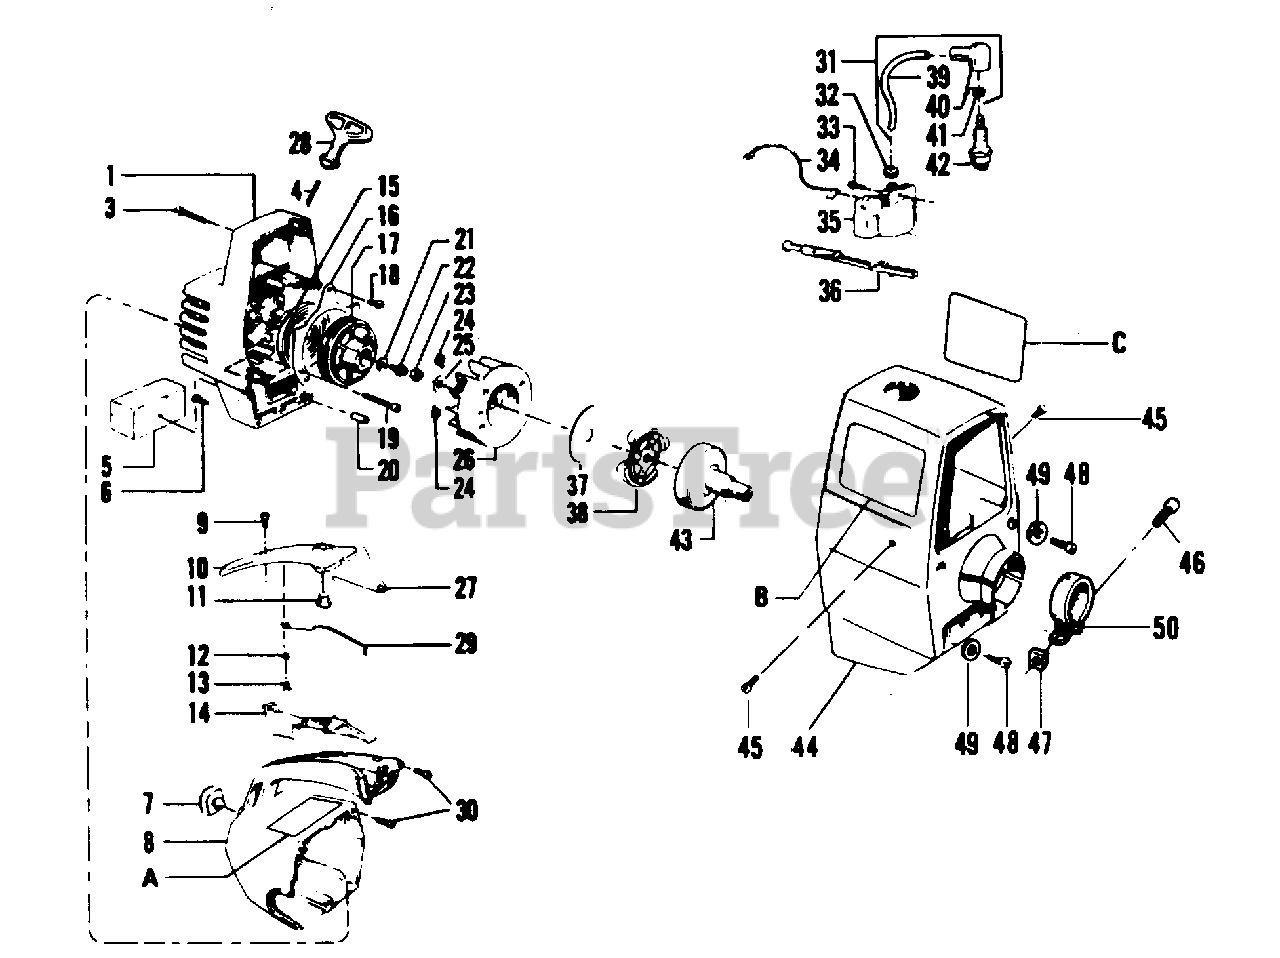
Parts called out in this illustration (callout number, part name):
1	Fan Housing Kit
3	Screw-10-16 x 1-5/8"-Plastite Fan Housing-Top
4	Rope Kit
5	Air Filter
6	Screw-10-24x5/8"-Sems-Fan Housing-Bottom
7	Bumper-Fuel Tank Housing
8	Handle & Fuel Tank Housing
9	Screw-8-16x3/4" - Pan Hd.-Handle Cover
10	Handle Cover
11	Kill Switch Button
13	Screw-8-16x3/8-Pan Hd.-Kill Switch
14	Throttle Trigger
15	Starter-Recoil Spring
16	Air Baffle
17	Starter Pulley
18	Screw #10-24x3/8"-Pan Hd.-Air Baffle
19	Screw-#10-24x1-3/16"-Plastite
20	Spacer-Air Baffle
21	Washer-Starter Pulley
22	Screw-#10-24x3/4"-Hex Washer Hd.-Starter Pulley
23	Nut-Flywheel
24	Spring-Starter Dog
25	Washer-Flywheel
26	Flywheel Assembly (Inc.24)
27	Trigger Spring
28	Starter Handle
29	Kill Switch Spring
30	Screw-10-14x3/4"-Pan Hd.-Fan Hsg. to Handle and Fuel Tank
31	High Tension Lead Ass'y (Inc.39, 40, & 41)
32	Grommet-Plug Wire
33	Screw-8-32x3/4"-Fil. Hd.-Ignition Module
34	Lead Wire-Switch
35	Module Kit
36	Choke Knob
37	Clutch Washer Kit
38	Clutch Ass'y Kit (Incl. Clutch Washer)
39	High Tension Lead Wire
40	Spark Plug Boot
41	Connector-Spark Plug Lead
42	Spark plug
43	Coupling and Bearing Assembly
50	Shroud Clamp
A	Decal-Starting Instructions
B	Decal-Shroud (Right)
C	Decal-Shroud (Left)
